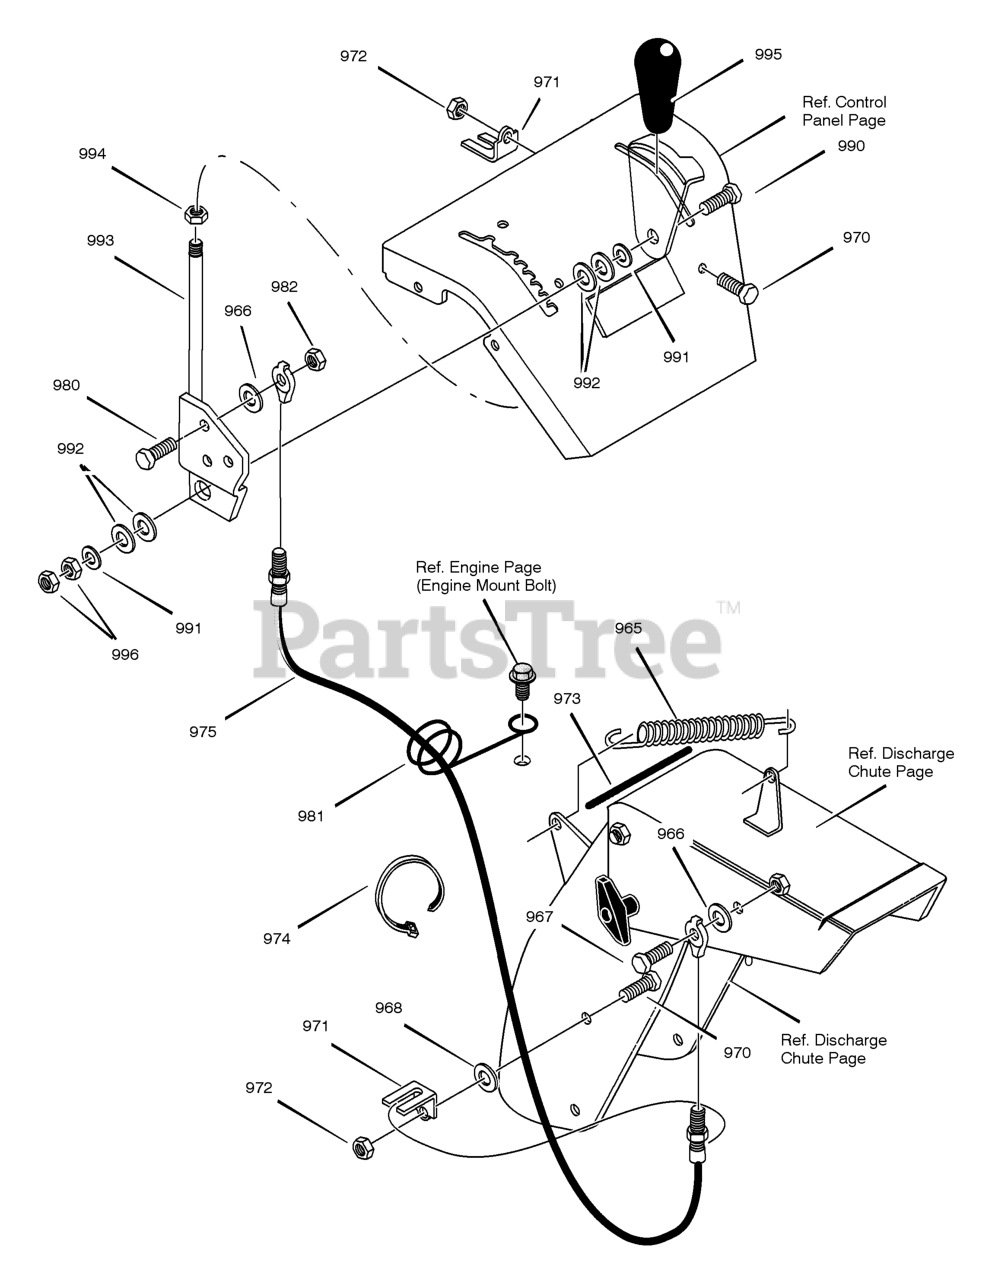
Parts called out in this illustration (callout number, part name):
965	TENSION SPRING
966	FLATWASHER
968	FLATWASHER
971	BRACKET, CABLE CHUTE
972	NUT
973	TRIM STRIP, GREY
974	TIE, CABLE
975	CABLE, CHUTE DEFLECTOR
981	WIRE FORM, REMOTE CHUTE CABLE
985	BRACKET, SNAP-IN REMOTE
990	SCREW
991	WASHER, FLAT
992	WASHER, SPRING
993	HANDLE, ASSY
995	KNOB, SHIFT (GREY)
996	NUT
